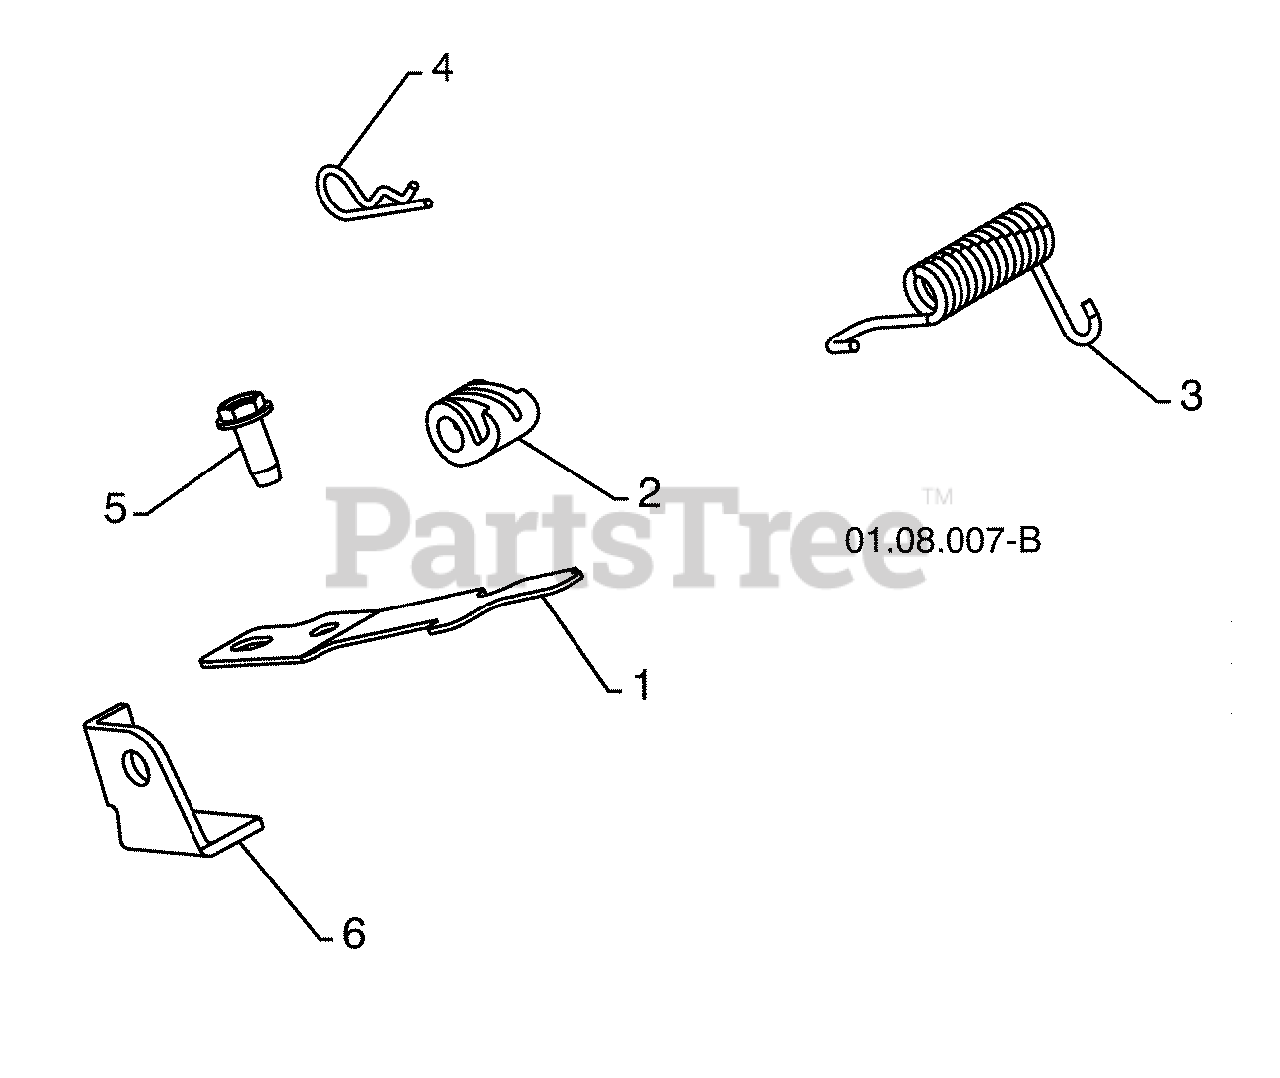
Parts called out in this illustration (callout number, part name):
1	INTERLOCK SPRING
2	INTERLOCK CAM
3	TORSION SPRING
5	SCREW 1/4-20 X .625
6	INTERLOCK STOP
